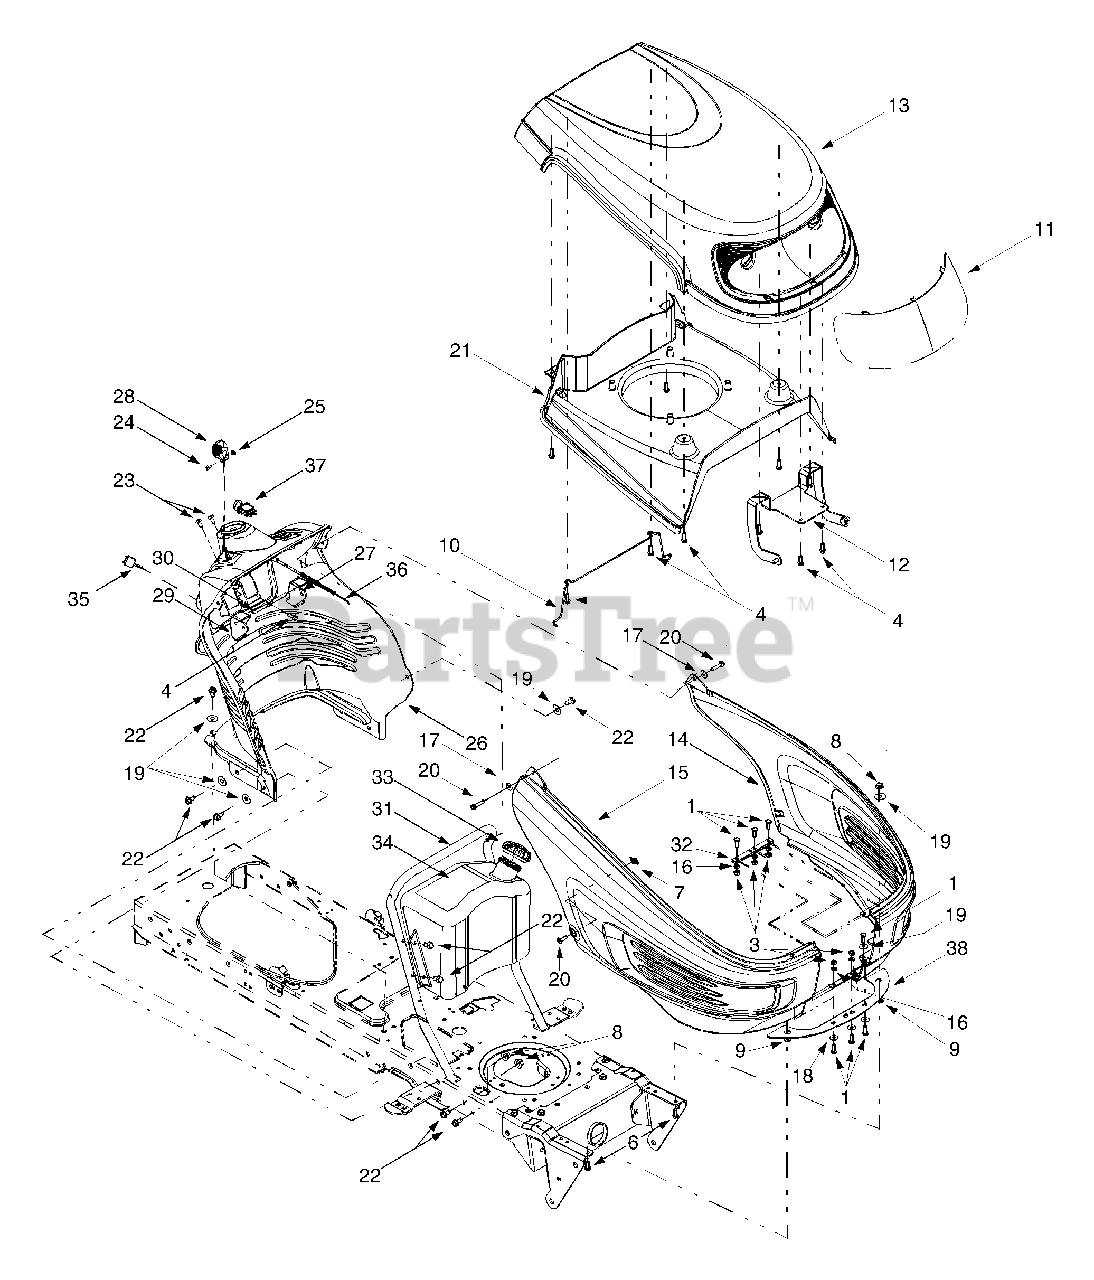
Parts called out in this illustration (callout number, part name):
1	Hex Cap Screw, 1/4-20 x .75
3	Hex Nut, 1/4-20
4	Self-tapping Screw, 1/4-15 x .75
6	Hex Cap Screw, 5/16-18 x 1.25
7	U-type Speed Nut, 1/4-20
8	Flange Lock Nut, 5/16-18
10	Hood Latch Rod
11	Head Light Lens
14	LH Side Panel
15	RH Side Panel
16	Lock Washer, 1/4
17	Flat Washer, .283 x .75 x .030
18	Flat Washer, .28 x .74 x .063
19	Flat Washer, .349 x 1.0 x .063
20	Self-tapping Screw, 1/4-20 x 1.25
22	Self-tapping Screw, 5/16-18 x .625
23	Torx Self-tapping Screw, 1/4-14 x .625
24	Torx Screw, #8-32 x .375
25	Hex Nut, 8-32
26	Dash Panel
27	Parking Brake Button
28	Throttle Control Lever
29	Cruise Control Button
30	Brake/Cruise Pivot Rod
34	Fuel Tank, 3-gallon
35	Ignition Key w/ plastic cover
36	Choke Cable
37	Electric PTO Switch
